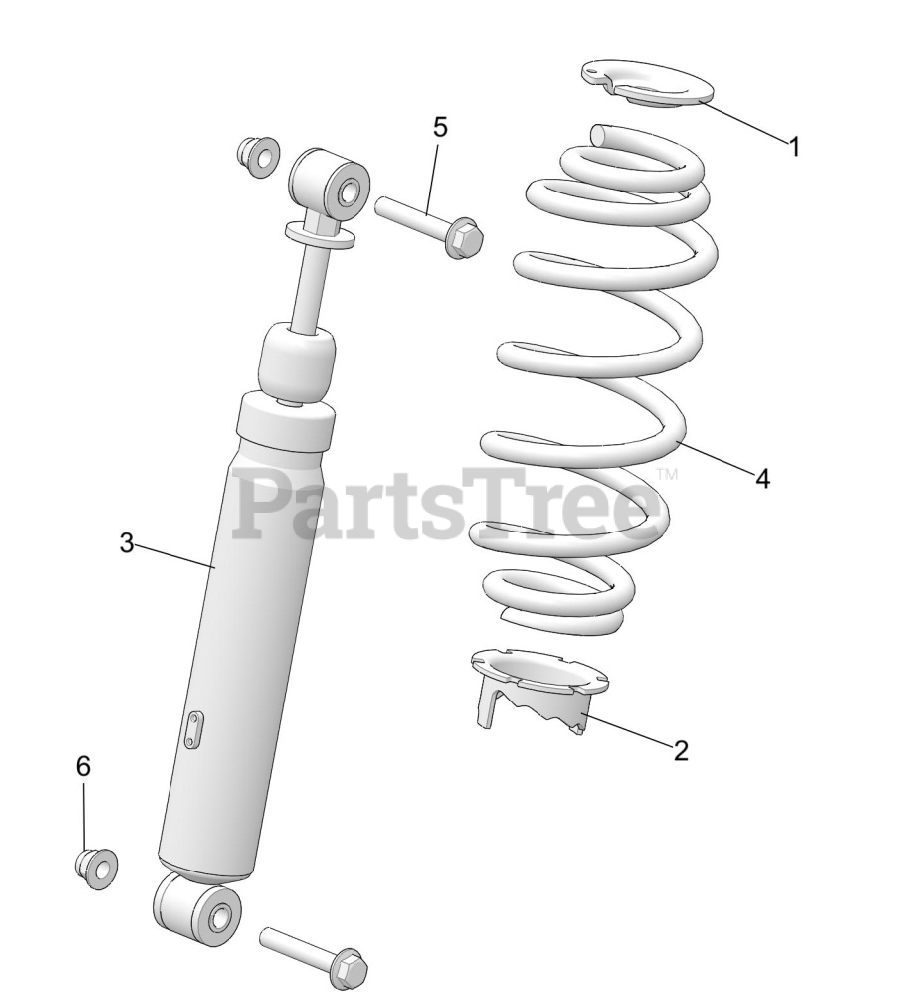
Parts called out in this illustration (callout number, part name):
1	RETAINER-SPRING-STEEL
2	CAM-ADJUSTING-SPRING-STEEL
3	SHOCK-FRONT
4	SPR-225-380#-12.1FL-2ID-M.BLK
5	SCR-HXFL-M10X1.25X60 10.9 ZOD
6	NUT-M10X1.25-FLG-NYLOC-OLIVE D
